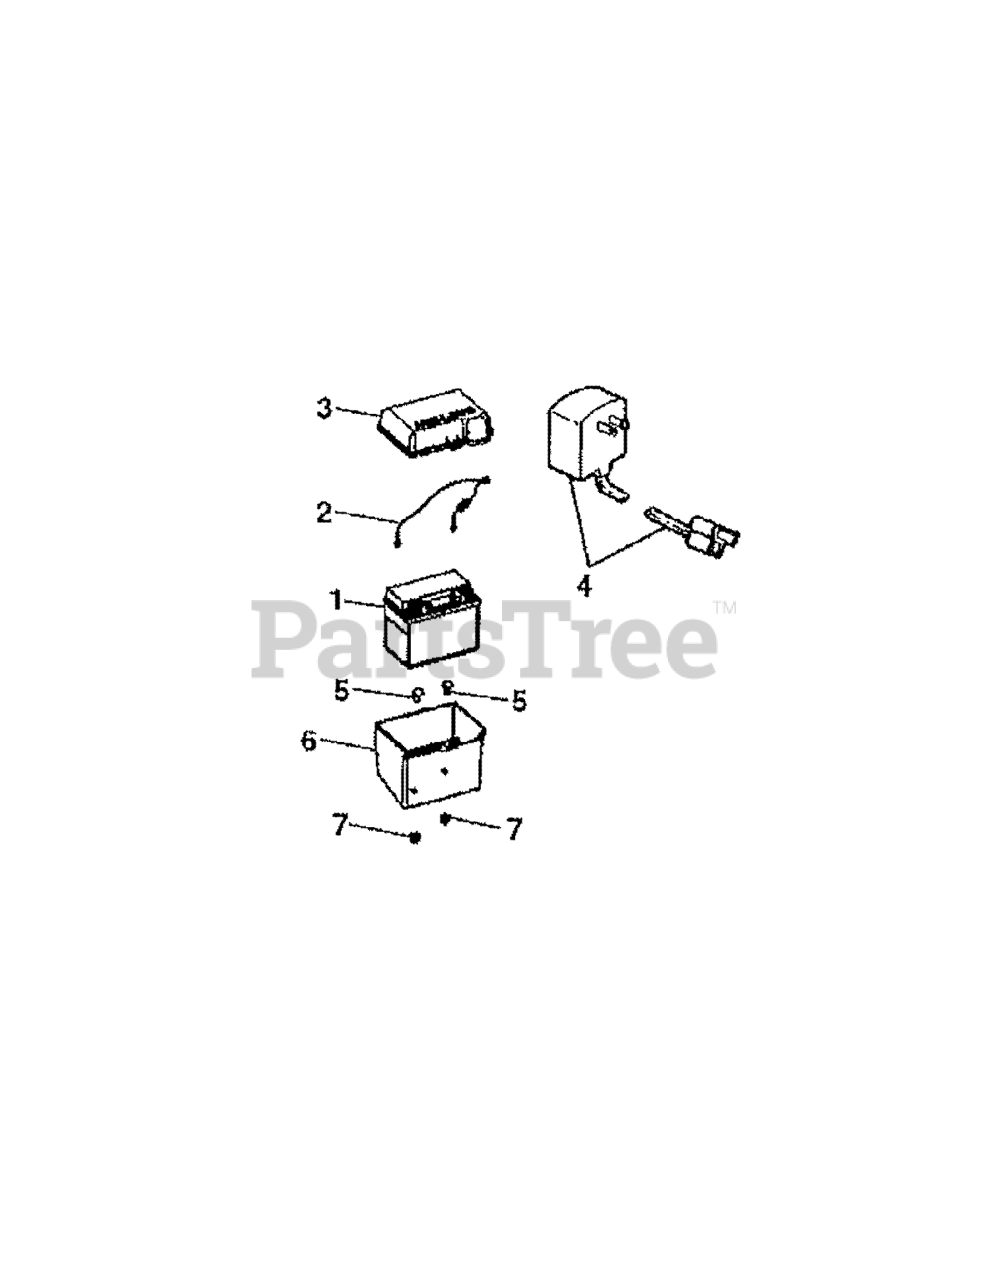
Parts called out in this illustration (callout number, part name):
1	ASSY, BATTERY (includes harness item #2)
2	HARNESS, BATTERY
3	TOP, BATTERY BOX - 21" JD WBM
4	CHARGER, BATTERY
5	FHSNB, 1/4-20X5/8
6	BOTTOM, BATTERY BOX - 21" JD WBM
7	NUT, HEX FLANGE, 1/4-20, ESNA, YZ
